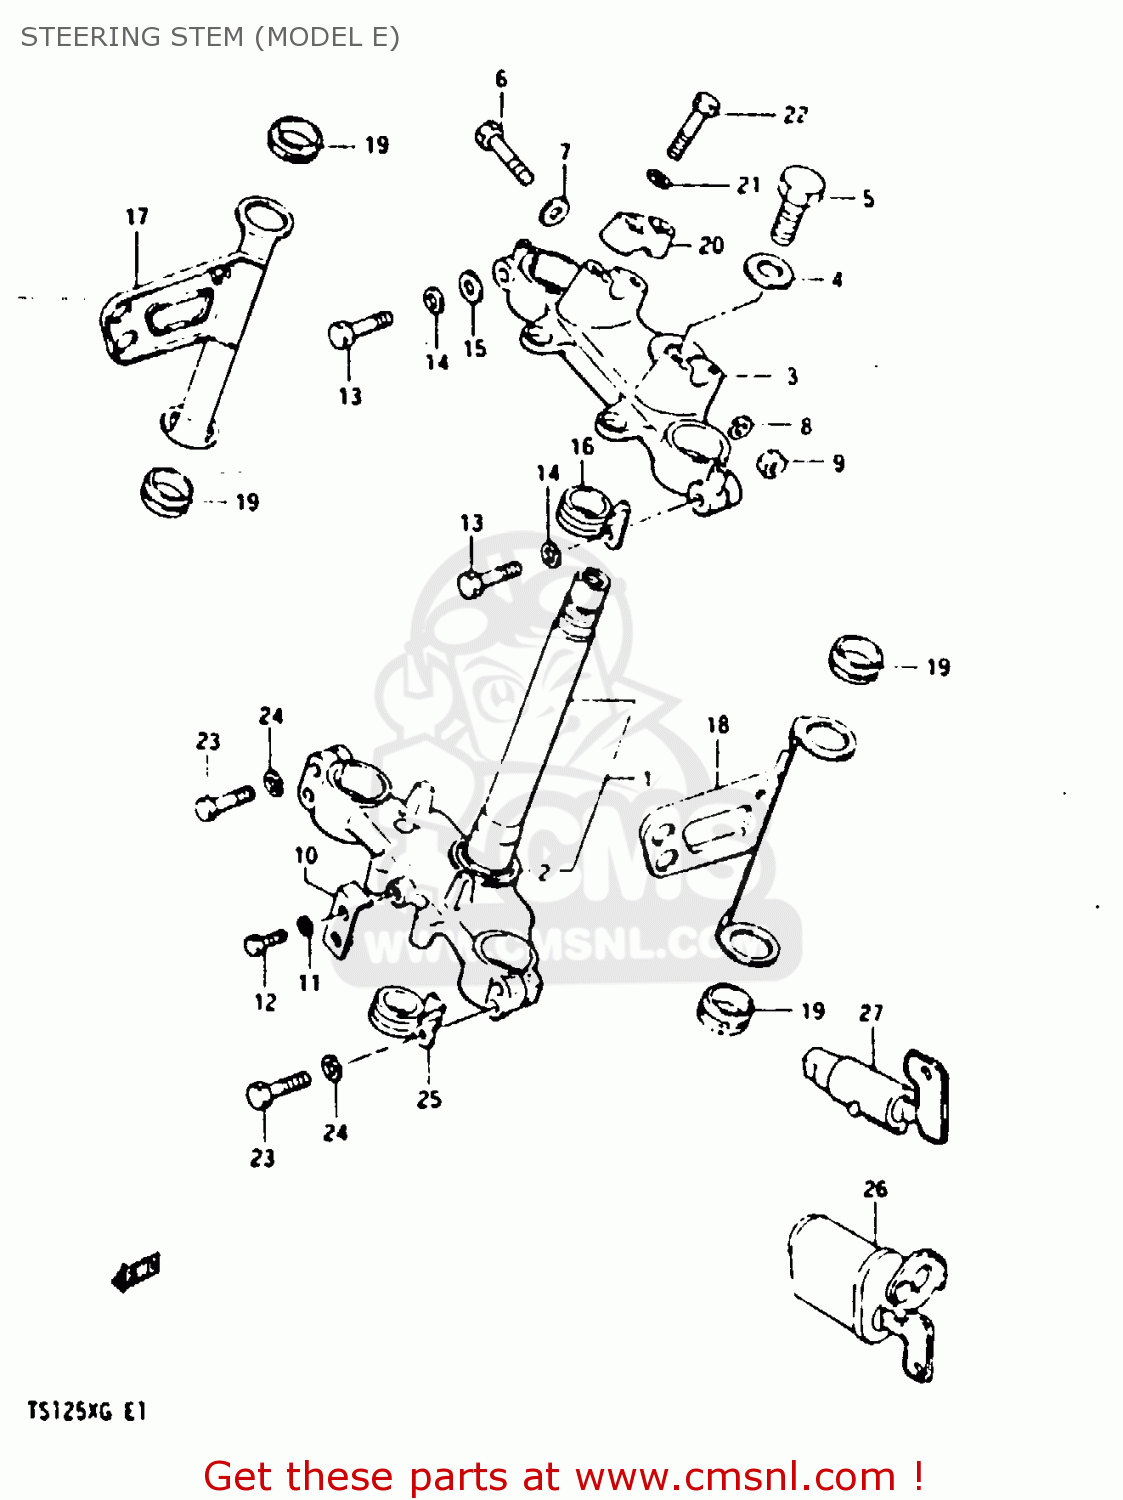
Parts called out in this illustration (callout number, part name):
1	STEM, STEERING (PEARL)
2	BEARING
3	HEAD, STEERING STEM
4	WASHER
5	BOLT,STEERING STEM
6	BOLT 8X50
7	WASHER
8	LOCK WASHER
9	NUT
10	PLATE
11	LOCK WASHER
12	BOLT
13	BOLT
14	LOCK WASHER
15	WASHER
16	CLIP
17	BRACKET, HEADLAMP RH
18	BRACKET, HEADLAMP LH
19	CUSHION,HEADLAMP HSG BRACKET
20	HOLDER,HANDLEBAR
21	LOCK WASHER
22	BOLT
23	BOLT 8X40
24	LOCK WASHER
25	CLIP
